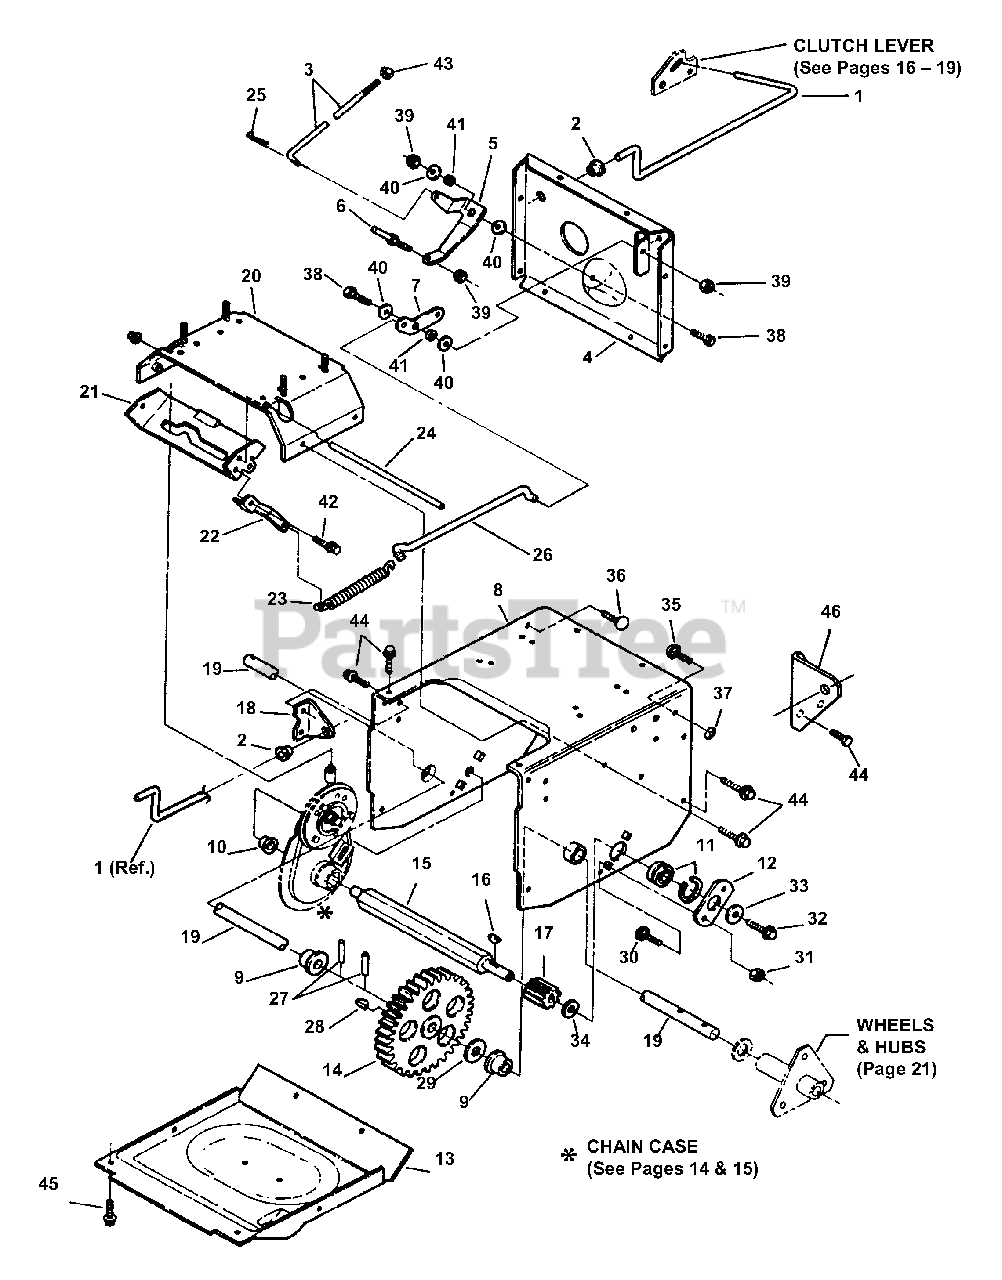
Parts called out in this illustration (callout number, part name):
1	ROD, Activating
2	BUSHING
3	ROD, Lower Shift
4	COVER, Frame Back
5	LEVER, Shift
6	STUD, Shift Lever
7	BELLCRANK, Traction
8	FRAME
9	BUSHING, Axle Shaft
10	BUSHING, Hex Shaft
11	BEARING
12	RETAINER, Bearing
13	COVER, Frame Bottom
14	GEAR, Axle Shaft
15	SHAFT, Hex
16	KEY, 1/8 x 5/8" Woodruff
17	PINION, Hex Shaft
18	BRACKET, Idler Mounting
19	SHAFT, Axle
20	BRACE, Frame
21	BRACKET, Clutch
22	BRACKET, Spring
23	SPRING
24	SHAFT, Cross
25	PIN, 3/32 x 3/4" Cotter
26	ROD, Push
27	PIN, 3/16" x 1-1/4" Roll
28	KEY, 3/16 x 7/8" Woodruff
29	WASHER, 3/4 x 1-1/8" Flat
30	BOLT, 1/4-20 x 1/2" Short Neck Carriage, Grade 5
31	NUT, 1/4-20 Hex Flange Lock
32	SCREW, 5/16-18 x 1/2" Hex Washer Self-Tap
33	WASHER, 5/16 x 1" Flat
34	WASHER, 5/8 Shim
35	BOLT, 5/16-18 x 3/4" Short Neck Carriage, Grade 5
36	BOLT, 5/16-18 x 1-1/2" Sqare Neck Carriage, Grade 5
37	RETAINER, 5/16 Bolt
38	SCREW, 5/16-18 x 3/4" Hex Head Cap, Grade 2
39	NUT, 5/16-18 Hex Center Lock, Grade B
40	WASHER, 5/16 x 1-1/4" Flat
41	SPACER, 5/16 x 5/8"
42	SCREW, 1/4-20 x 3/8" Hex Washer Self-Tap
43	NUT, 3/8-16 Hex, Grade B or 5
44	SCREW, 5/16-18 x 5/8" Hex Washer Self-Tap
45	SCREW, 1/4-20 x 5/8" Hex Washer Self-Tap
46	BRACKET, Worm Shaft
